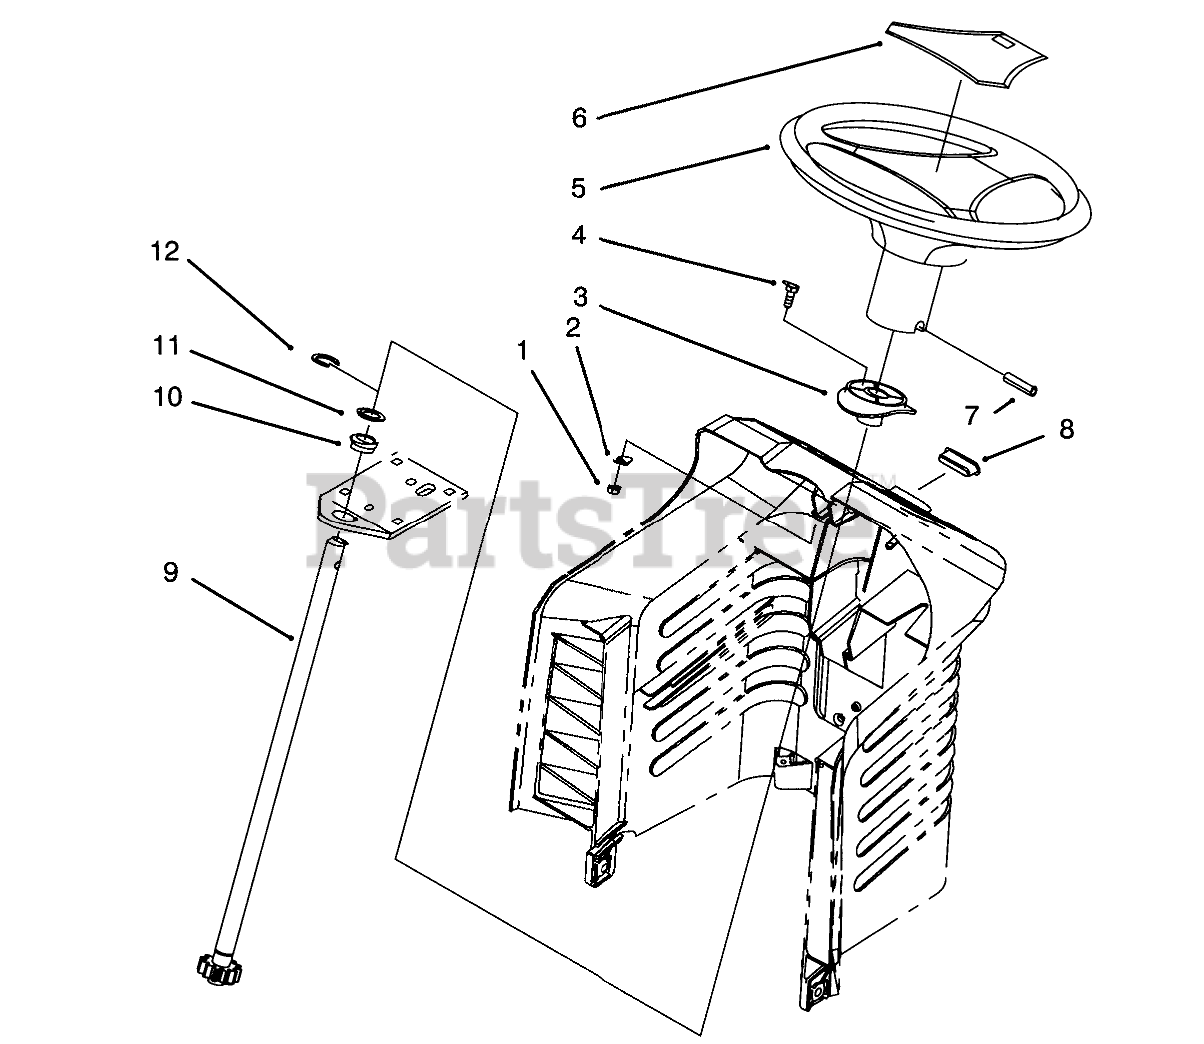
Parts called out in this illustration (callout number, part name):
1	NUT-LOCK, NI
2	WASHER-FLAT
3	BUSHING-SLIDING
4	SCREW-HH
5	Wheel-Steering (Incl. Ref. #6)
6	COVER-WHEEL
7	PIN-ROLL
9	SHAFT-STEERING, LONG
10	BEARING-FLANGE
11	WASHER-THRUST
12	E-RING
